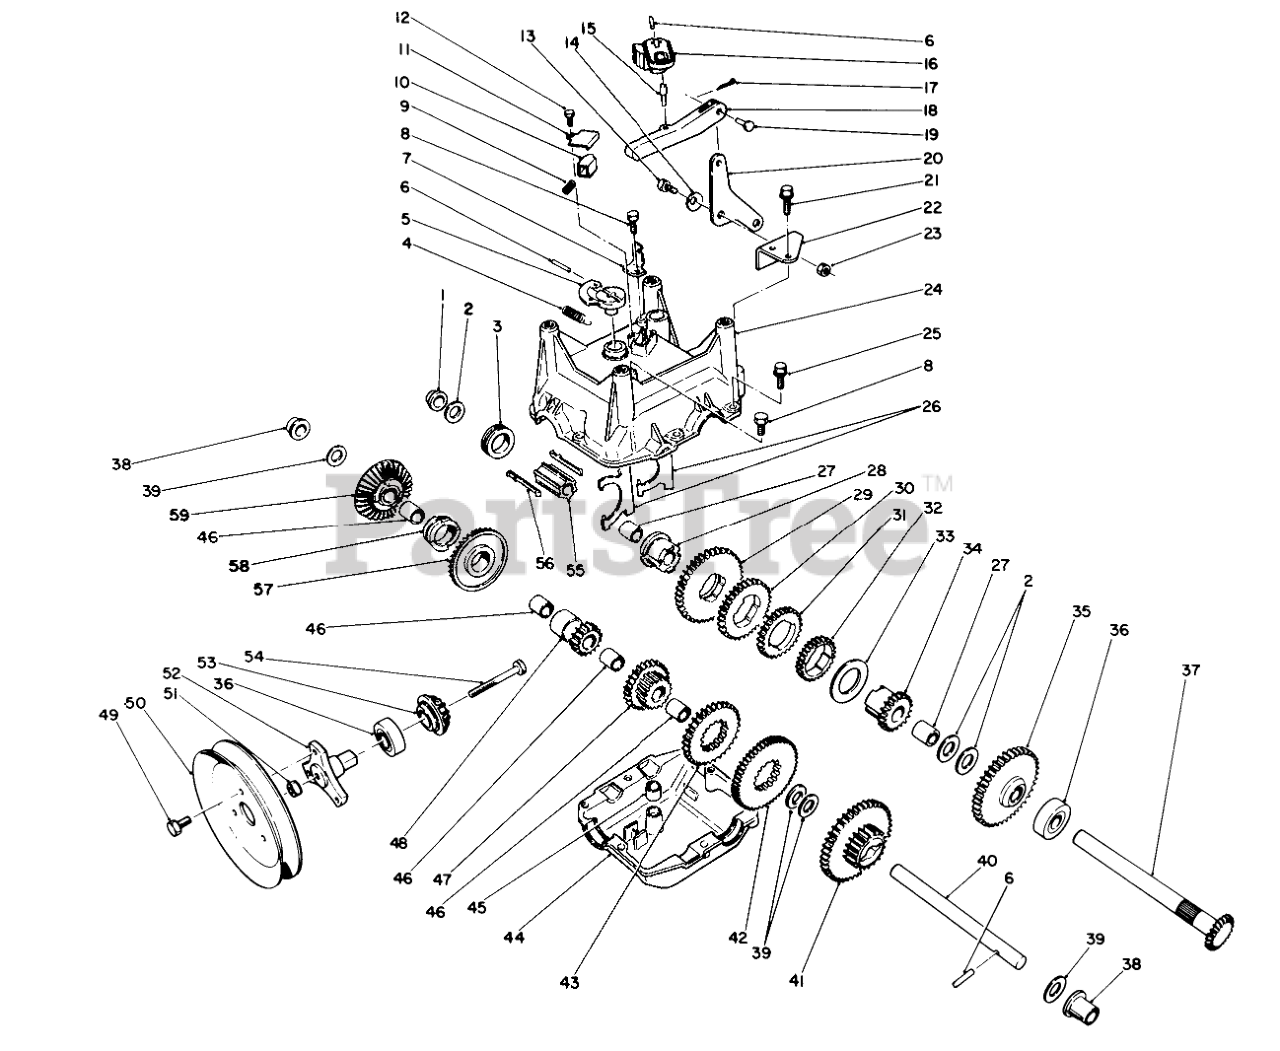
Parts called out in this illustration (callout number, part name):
1	BUSHING-FLANGE, OUTPUT
2	BEARING-THRUST
3	COLLAR-SHIFT
4	SPRING-EXTENSION
5	LEVER
6	PIN-SPRING
7	BRACKET-CABLE
8	SCREW-HWH
9	SPRING-DETENT
10	BUTTON-DETENT
11	COVER-DETENT
12	SCREW-HWH
13	SCREW-SHOULDER
14	WASHER-CURVED
15	PIN-LINK, GEAR SHIFT
16	LEVER-SHIFT, GEAR
17	PIN-COTTER
18	LINK-SHIFT, GEAR
19	PIN-CLEVIS
20	BELLCRANK
21	SCREW-HWH
22	BRACKET-BELLCRANK
23	NUT-LOCK, NI
24	GEARCASE-UPPER, CASING
25	SCREW-HWHTF
26	YOKE-SHIFT
27	BUSHING-OUTPUT
28	SLEEVE-GEAR
29	GEAR-45 T
30	GEAR-34 T
31	GEAR-27 T
32	GEAR-29 T
33	WASHER-THRUST
34	GEAR-SLEEVE, 19 T
35	GEAR-41 T
36	BEARING-BALL
37	SHAFT-OUTPUT
38	BUSHING-INTERMEDIATE
39	WASHER-THRUST
40	SHAFT-INTERMEDIATE
41	GEAR-19/41 T
42	GEAR-51 T
43	GEAR-33 T
44	GEARCASE-LOWER, CASING
45	BUSHING-YOKE
46	Bushing-Output
47	GEAR-26 T
48	GEAR-BEVEL, 15 T
49	SCREW
50	TRACTION-SHEAVE, HALF
51	NUT-HHF
52	HUB-PULLEY
53	PINION-BEVEL
54	SCREW-HH
55	SLEEVE-SHIFT
56	KEY-SHIFT
57	GEAR-BEVEL, 36 T
58	COLLAR-SHIFT
59	Gear-Bevel Reverse 36T (Incl. Ref. #46)
